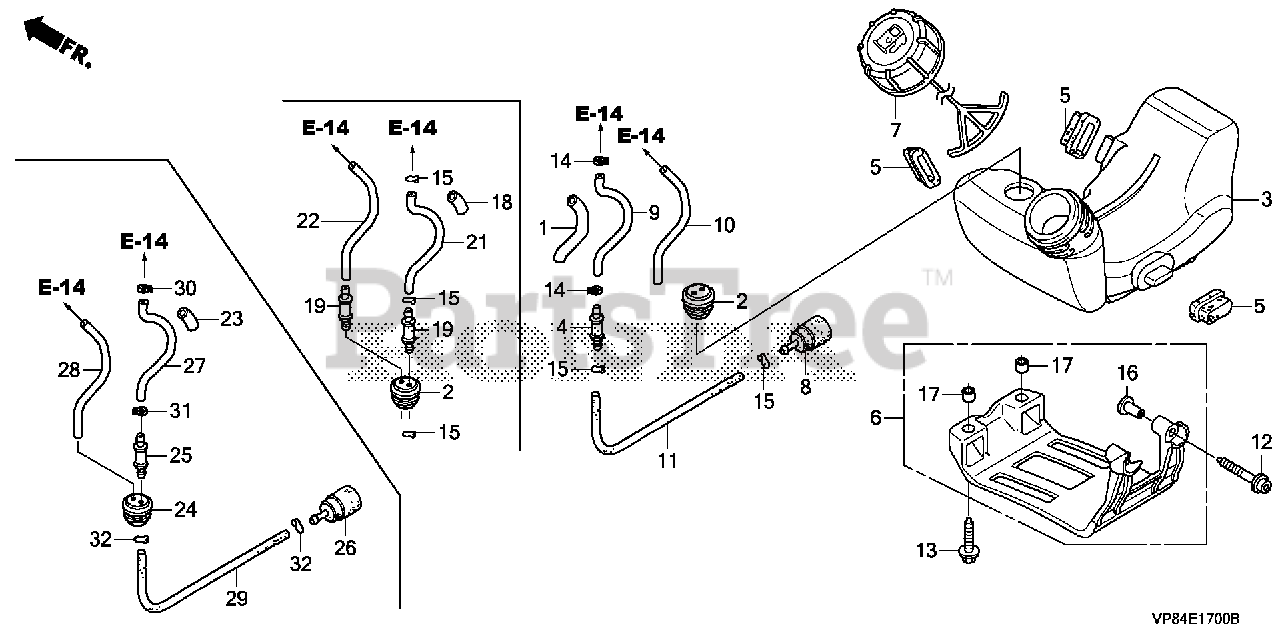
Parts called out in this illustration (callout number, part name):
3	TANK, FUEL
5	RUBBER, TANK MOUNTING
6	GUARD, TANK
7	CAP ASSY., FUEL TANK
12	BOLT, SOCKET (5X30)
13	BOLT, SOCKET (5X16)
16	COLLAR, TANK GUARD
17	COLLAR A, HEAD COVER
23	PROTECTOR, TUBE
24	GROMMET, FUEL TUBE
25	JOINT, FUEL TANK
26	FILTER, FUEL
27	TUBE, FUEL
28	TUBE, FUEL RETURN
29	TUBE A, FUEL
30	CLAMP, TUBE (D5.5)
31	CLAMP, TUBE (D5.5)
32	CLIP, TUBE (B1 5)
